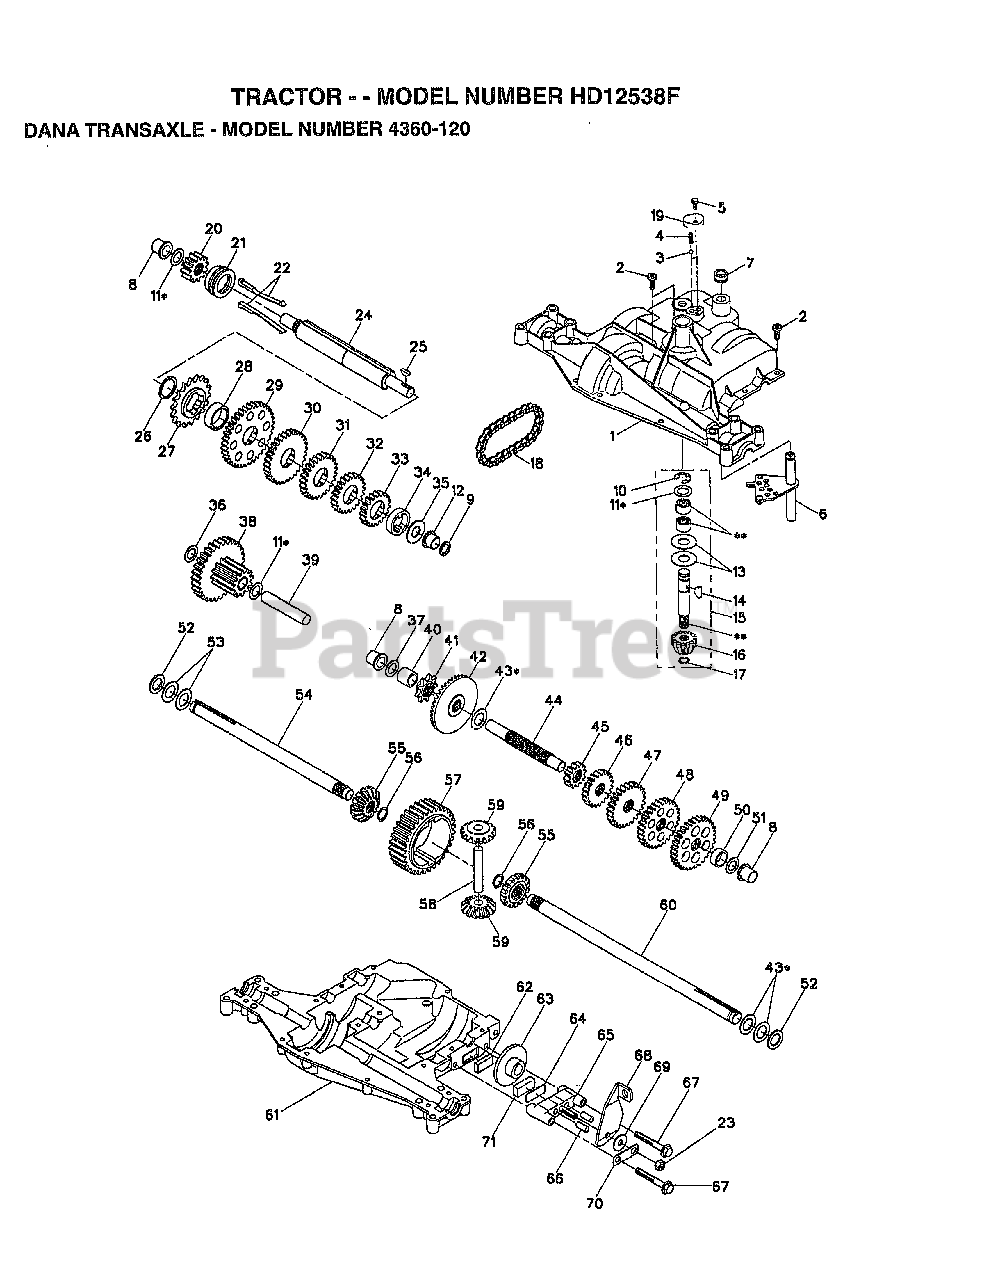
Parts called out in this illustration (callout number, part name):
1	HOUSING.UPPER.DANA.(5305J)
4	"SPRING, DETENT LT"
5	SCREW.TAPPING.1/4-20X.734
6	KIT SHIFTER ASM
9	SEAL.OIL.DAN.5508
10	RETAINING RING LT
11	ASM KIT SHIM 4689
12	BEARING.FLNG.5511
13	WASHER T
14	KEY WOODRUFF-DANA
15	INPUT SHAFT KIT 6250
16	PINION.BEVEL.12T(5620)
17	"RING,RETAINING LT"
18	"CHAIN,24 PTCH LT"
19	COVER.DETENT.(5584)
20	GEAR.SPUR.12T.(5627)
21	CLUTCH.COL.5467
22	ASM KIT CLTCH KEY
23	NUT.LOCK.5/16-24
24	SHAFT INTERM DANA
25	WOODRUFF KEY
26	"RING,RETAINING LT"
27	SPROCKET 18T T
28	SPACER YT
29	GEAR SPUR 37 TTH
30	GEAR SPUR 30T
31	GEAR 25T LT
32	GEAR SPUR 22 TT
33	SPUR GEAR 19T
34	SPACER
35	"WASHER, PLAIN LT"
36	WASHER 045
37	WASHER 031
38	ASSY.GEAR.6153 12T&30T
39	SHAFT IDLER
40	SPACER T
41	SPROCKET 9T LT
42	GEAR.BEVEL.36T(5621)
43	ASM KIT SHIM
44	SHAFT T
45	GEAR SPUR 12 TTH
46	GEAR SPUR 20T
47	"GEAR, SPUR 25T LT"
48	GEAR 28T T
49	"GEAR, SPUR 31T LT"
51	WASHER 060
52	NEOPRENE WASHER
53	WASHER 031
54	AXLE.LH(5528-1)
55	MITER 5270 12T.SPLINED
56	RING.RETAINING.(5270)
58	SHAFT T
59	MITER 5623.12T.IDLER
60	AXLE.RH.(5528-2) DANA
61	HOUSING LOWER TNS
62	PUCK T
63	BRAKE DISC. T
64	SPACER LT
66	PIN T
67	SCREW.(5562) .5/16-18X2.35
69	WASHER LT
70	BRACKET, ANTI-ROTATION
71	PUCK T
